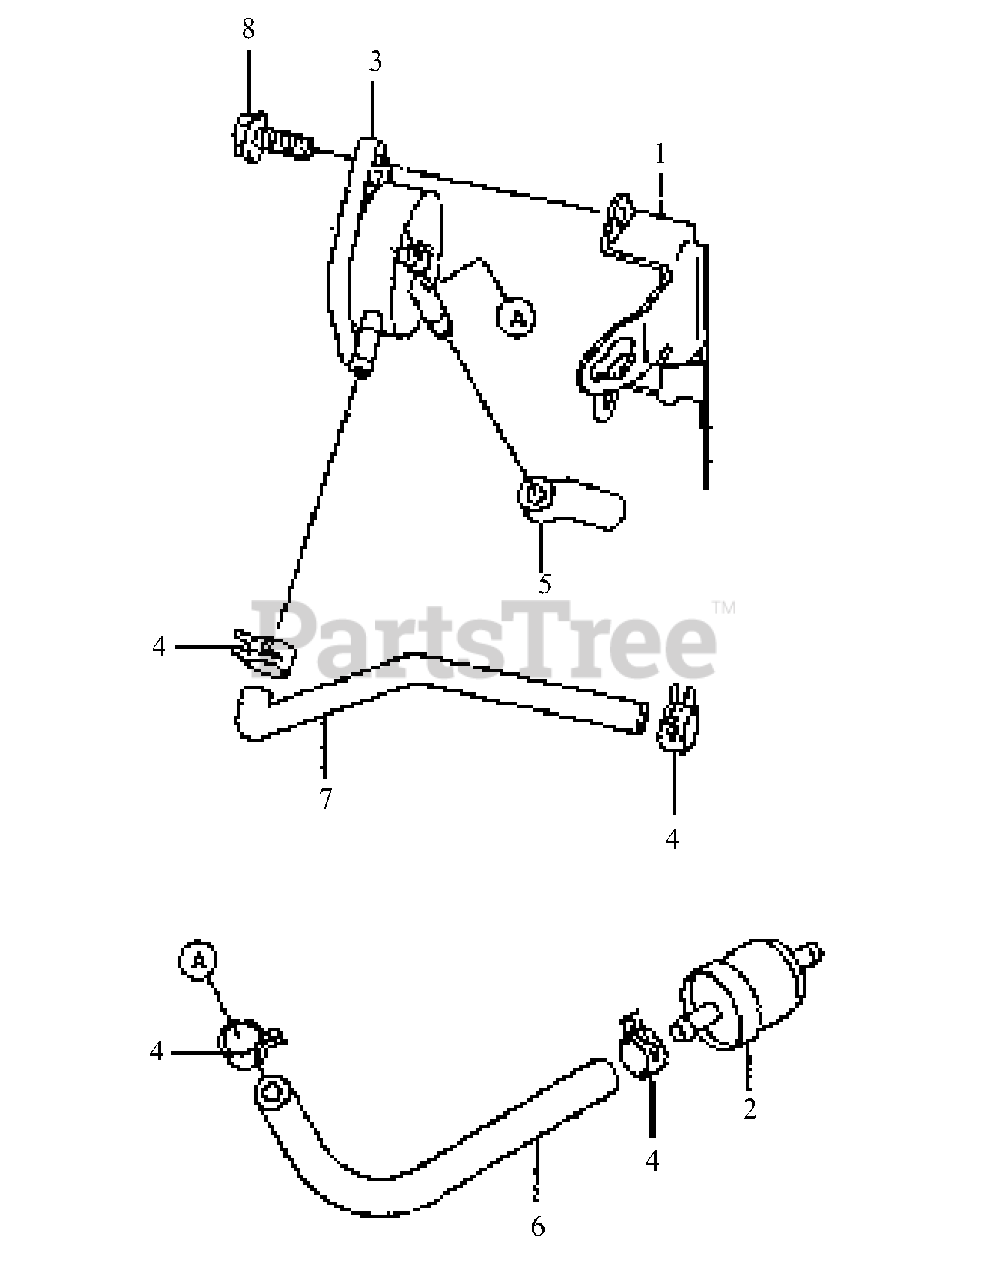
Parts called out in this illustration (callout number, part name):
2	Filter, Fuel
3	Pump, Fuel
4	Clamp
6	Tube 6.35x12.7x160
8	Bolt, Flange
